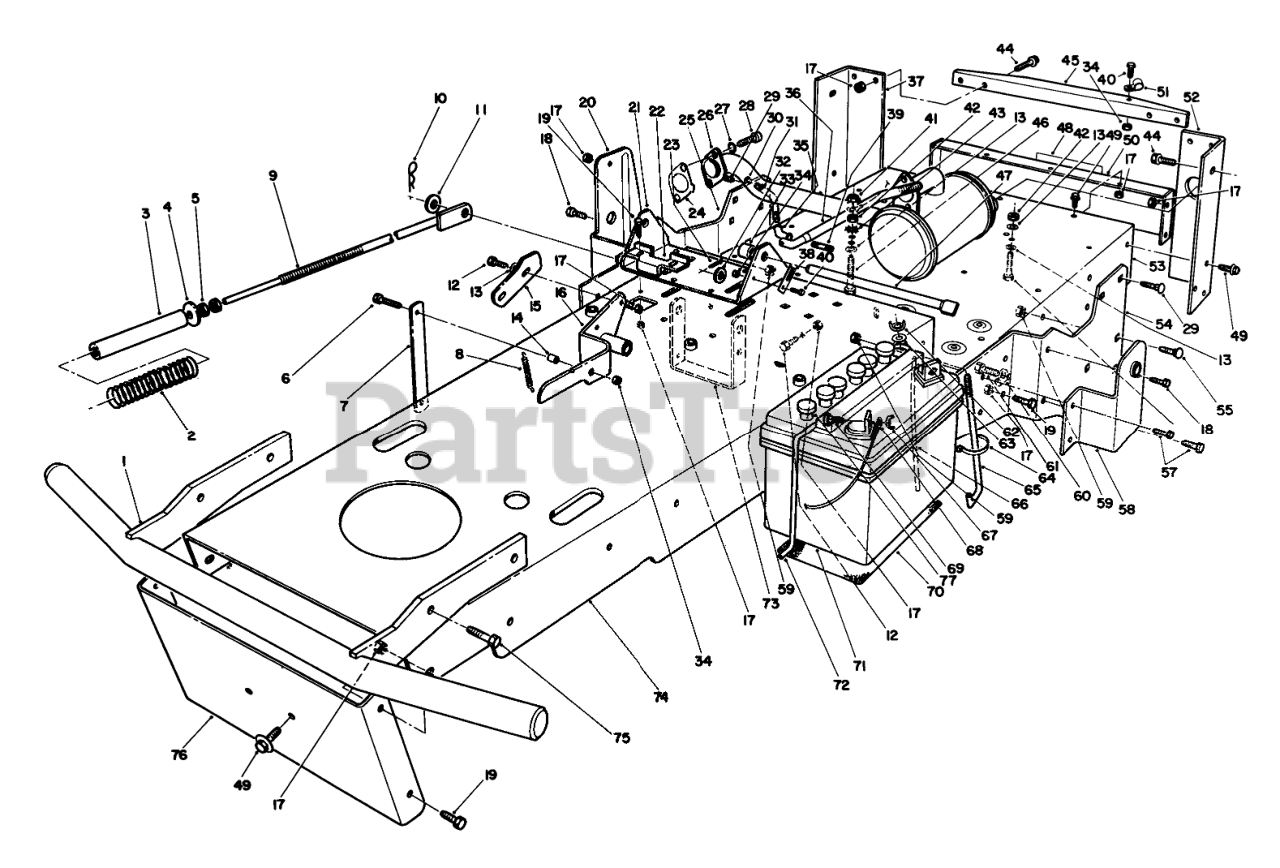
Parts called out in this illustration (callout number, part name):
1	BUMPER WA B
2	COMP. SPRING
3	TUBE SLEEVE
4	WASHER
5	NUT-JAM
6	SCREW-HH
7	PARKING BRAKE LINK B
8	EXTENSION SPRING
9	BELT TENSION ROD WA
10	PIN-HAIR
11	WASHER-FLAT
12	SCREW-HH
13	WASHER-PLAIN
14	SPACER
15	SHIFT STOP B
16	PARKING BRAKE LVR WA B
17	NUT-LOCK, NI
18	SCREW-HH
19	SCREW-HH
20	RH PIVOT BRACKET B
21	PIVOT BRACKET B
22	PARKING BRAKE STOP
23	PIN-COTTER
24	EXHAUST GASKET F/W ENG.
25	RH SPLICE PLATE WA
26	MUFFLER
27	WASHER-LOCK
28	SCREW-HSH
29	BOLT-CARR
30	CAP-PIPE
31	8 HP DRAIN TUBE
32	WASHER-FLAT
33	SPACER
34	NUT-LOCK, NI
35	ELBOW - 45 DEGREES
36	BRAKE ROD
37	RH REAR CORNER POST B
38	RETAINER-SHAFT
39	NIPPLE-PIPE
40	SCREW-HH
41	NUT-KEPS
42	NUT-HEX, SIDE DEFORM
43	WASHER-LOCK
44	SCREW-HHF
45	Guard-Rear
46	SCREW-HH
47	PARKING BRAKE SHAFT
48	DECAL - TRAILER HITCH
49	SCREW-HHF
50	HITCH PLATE
51	CLIP-CLOSED, INSULATED
52	LH REAR CORNER POST B
53	REAR FRAME WA
54	LH SPLICE PLATE WA
55	BOLT-CARR
56	SCREW-HH
57	SCREW-HH
58	LH PIVOT BRACKET B
59	NUT-LOCK, NI
61	SCREW-HH
62	NUT-WING
63	WASHER-FLAT
64	TIE-CABLE
65	POST-BATTERY
66	TUBE-VENT
67	NUT-WING
68	WIRE ASM
69	BOLT-CARR
70	PAD-SKID, ANTI
71	Battery
72	BATTERY HOLD DOWN
73	BRAKE U BRACKET B
74	FRONT FRAME WA
75	SCREW-HH
76	FRONT COVER B
77	NON-VENTED BATTERY CAP
